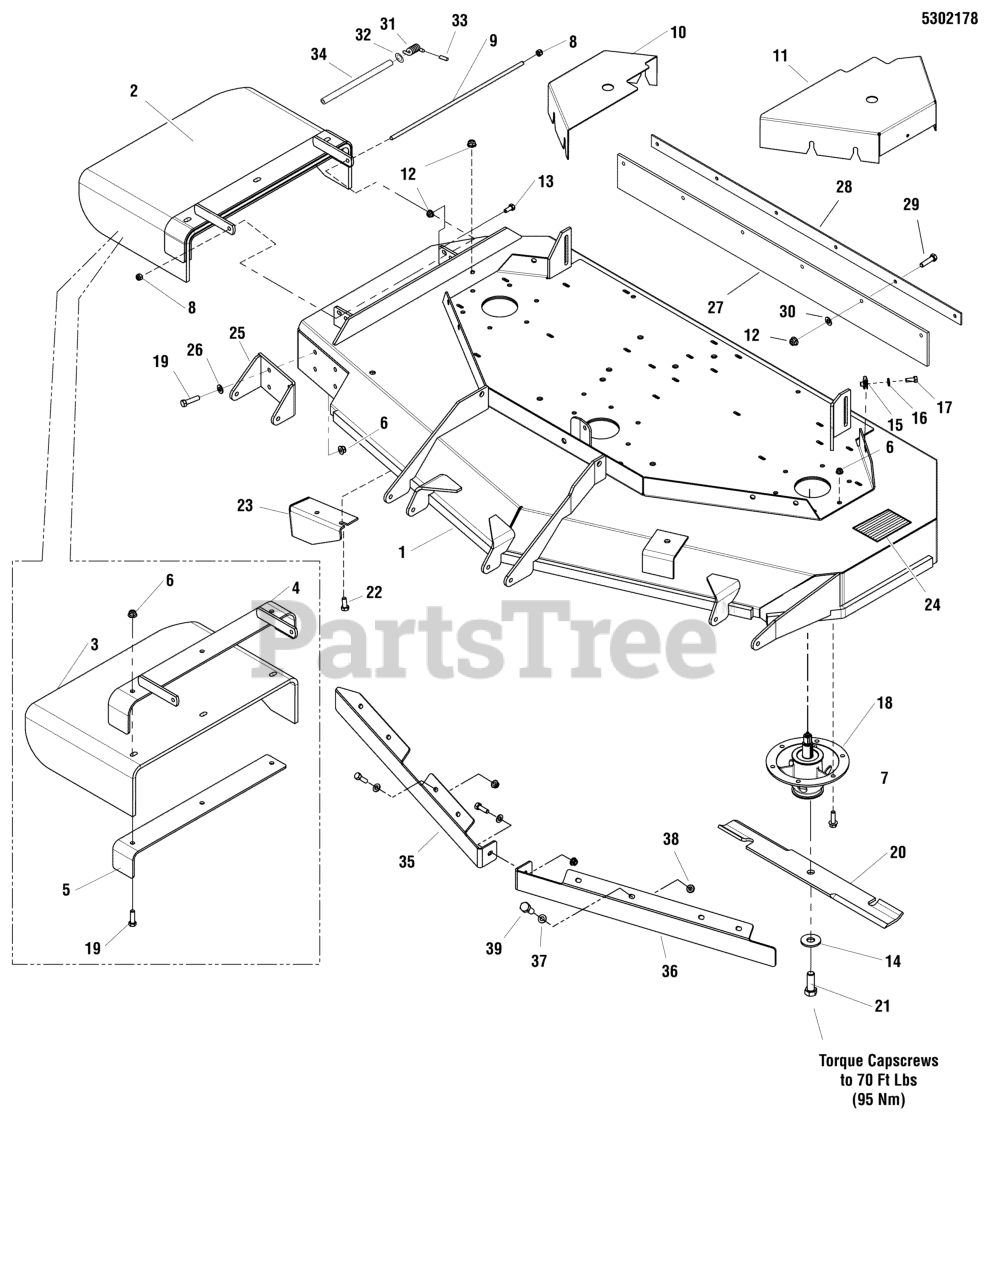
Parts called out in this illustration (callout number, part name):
1	DECK SHELL W/ DECALS, S175X 61
1	DECK SHELL W/ DECALS, S175X 61 CE
2	PURCHASE INDIVIDUAL REPLACEMENT PARTS
3	CHUTE, DISCHARGE, BEND RUBBER (SV)
4	WELD, FRAME CHUTE, 61 - BLK
5	SUPPORT, DISCHARGE CHUTE, 61/72 - BLK
6	NUT, 3/8-16 HEX NYLOCK FLANGE
7	BOLT, 3/8-16 X 1" GD5 CZ
8	NUT, 5/16-24 HEX NYLON LOCK
9	ROD MOUNT, CHUTE 61"
10	GUARD, 61", RH - RED
11	GUARD, 61" - LH - RED
12	NUT, 5/16-18 HEX NYLOCK FLANGE
13	BOLT, 5/16-18 X 3/4 GD5
14	WASHER, 5/8" GRADE 8, YZ
15	BODY CLIP, 5/16-18-7GA MATERIAL
16	WASHER, 5/16" SAE
17	BOLT, 5/16-18 X 3/4 GD5
18	ASSM, SPINDLE, CAST IRON
19	BOLT, 3/8-16 X 1-1/2" GD5 CZ
20	BLADE, 21" (SET OF 3)
21	BOLT, 5/8-11 X 1-3/4" GD8
22	BOLT, 5/16-18 X 3/4, CARRIAGE
23	PLATE, DEFLECTOR - BLK
24	SAFETY WALK, 9.75 X 6.00
25	PLATE, BRACKET, ANTI SCALP - RED
26	WASHER, 3/8 SAE
27	FLAP, STRIPER, 61 DECK
28	PLATE, SUPPORT - BLK
29	BOLT, 5/16-18 X 1" GD5
30	5/16 PUSH-ON NUT RETAINER, STL, CZ
31	SPRING, TORSION
32	WASHER, 5/16 FENDER
33	CAP, PROTECTOR, .120 ID
34	TUBE, 1/2 X 3/8 X 10.75 BLACK POLY
35	BAFFLE, BLOWOUT, 61 ICD, RH - BLK
36	BAFFLE, BLOWOUT, 61 ICD, LH - BLK
37	WASHER, 5/16" SAE
38	NUT, 5/16-18 HEX NYLOCK FLANGE
39	BOLT, 5/16-18 X 1 GD5 YZ
